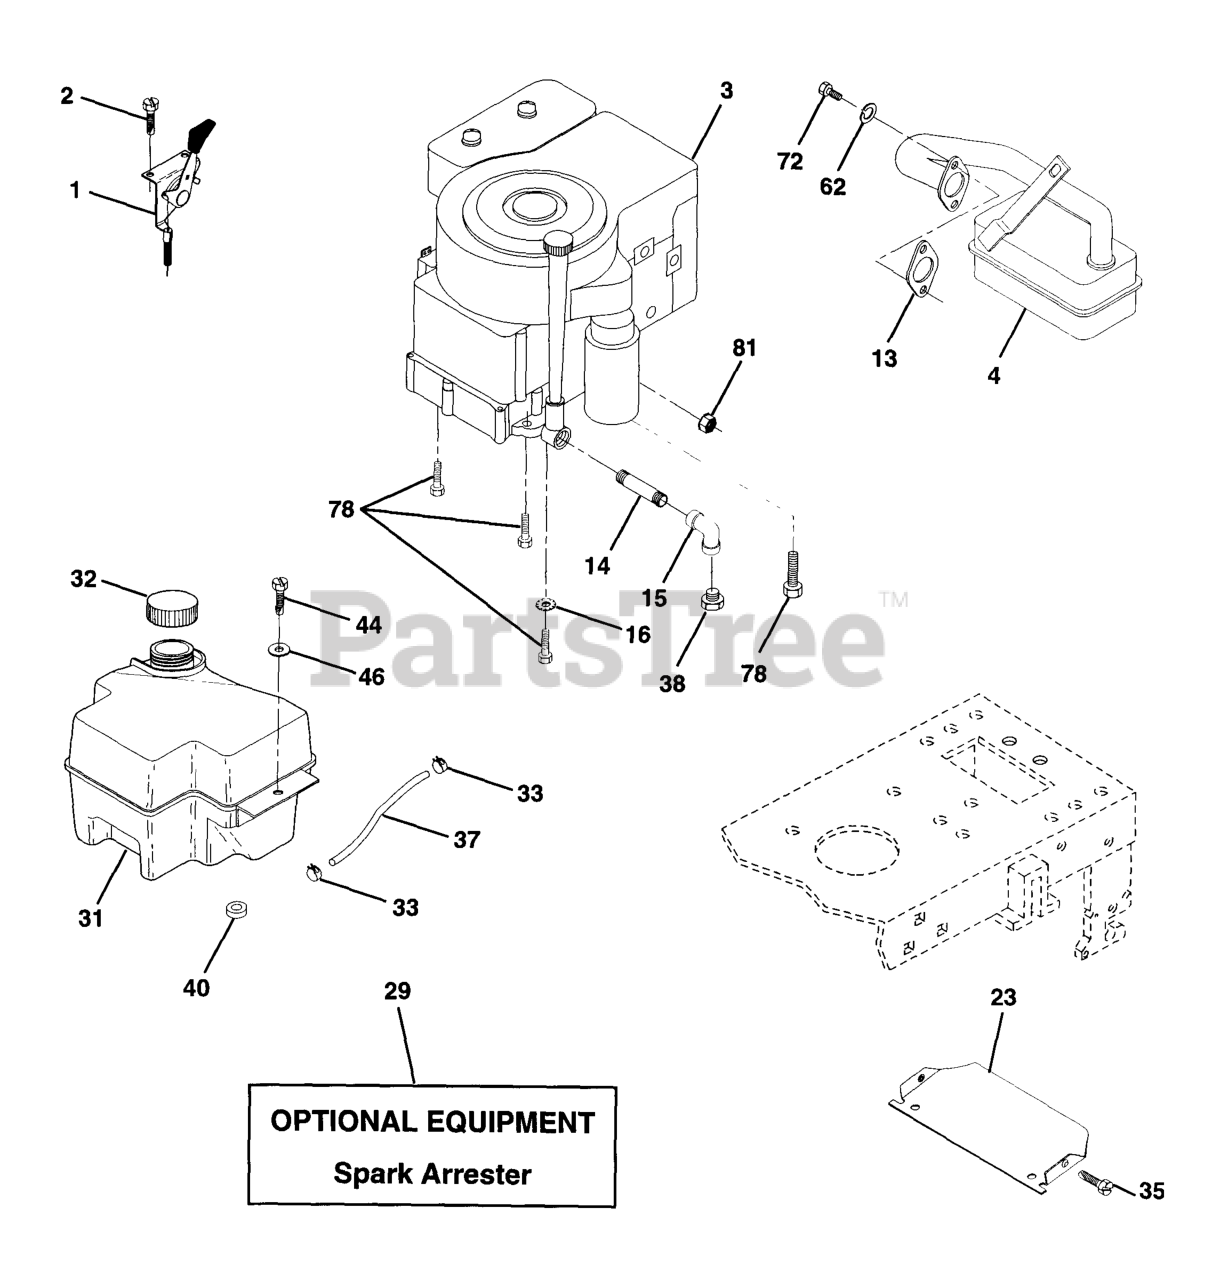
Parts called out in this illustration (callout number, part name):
1	CHOKE CONTROL
2	SCREW LT
4	MUFFLER.SINGLE.B&S.10-12HP
13	GASKET.ENG.1.313 ID.TIN PLATED
14	Nipple Pipe 3/8 Npt X 3"
15	ELBOW
16	LOCKWASHER
23	SHIELD HEAT
29	KIT.SPARK ARRESTOR 794945 B&S
31	FUEL TANK
32	FUEL CAP
33	HOSE CLAMP
35	SCREW.THDROL.5/16-18X3/4.TTY
37	LINE.FUEL.20
38	Plug Oil Drain
40	BUSHING.SNAP.NYL.BLK.
44	SCREW HEX CRT
46	WASHER
62	WASHER.LOCK.HVY.HLCL.SPR.5/16
72	SCREW
78	SCREW
81	NUT FLANGE 1/4-20 STARTER NUT
